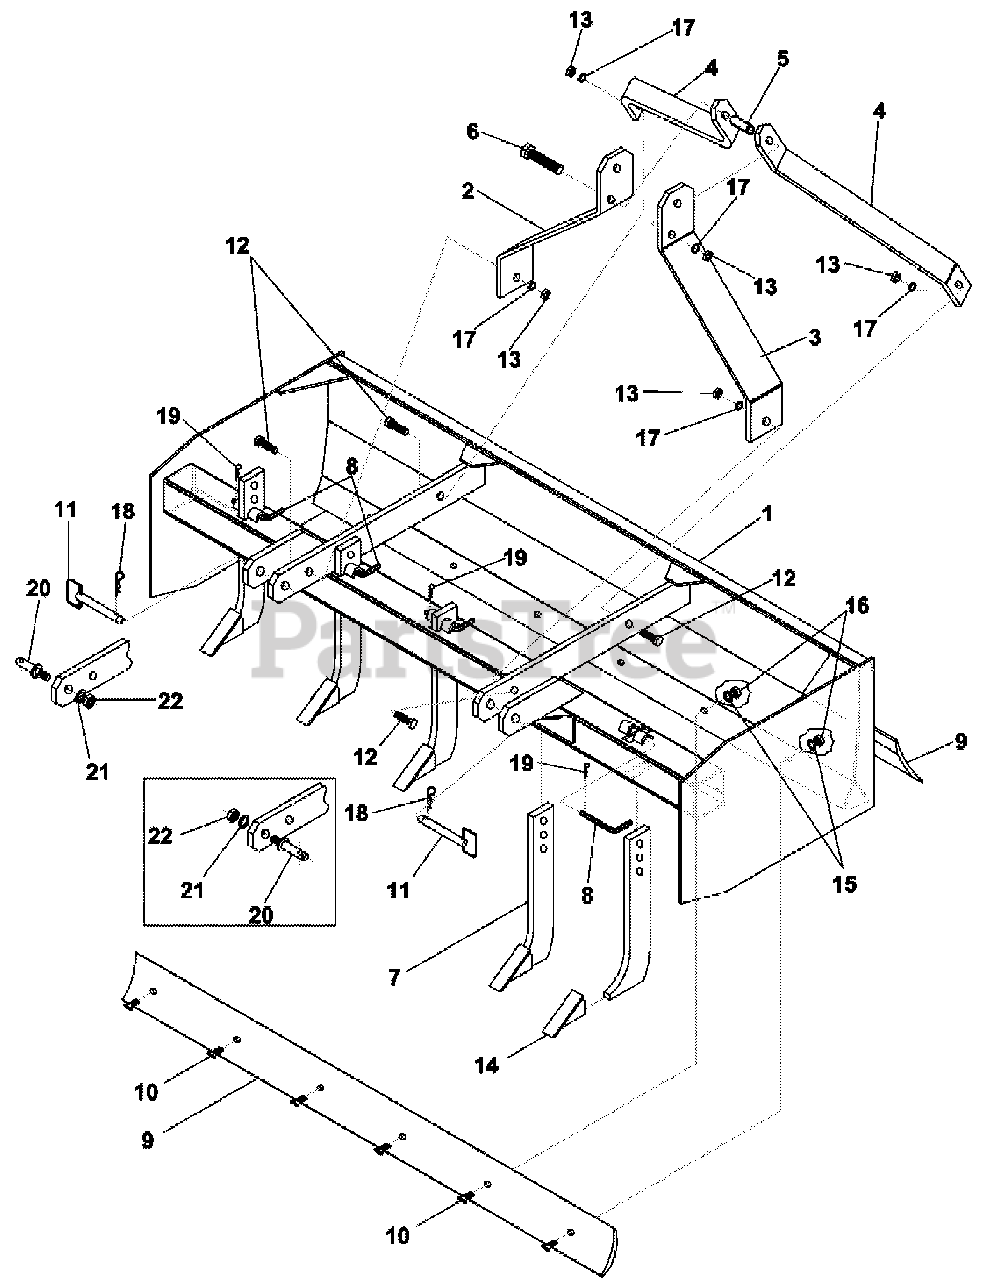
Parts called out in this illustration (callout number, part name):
1	Frame subcompact BS48
2	Vertical support right BS48
2	Vertical support right BS60 & BS72
3	Vertical support left BS48
3	Vertical support left BS60 & BS72
4	Horizontal support BS48
4	Horizontal support BS60 & BS72
5	Inner spacer BS48
5	Inner spacer BS60 & BS72
6	Bolt 3/4"x4.5" BS48
6	Bolt 3/4"x5" BS60 & BS72
7	Scarifier shank
9	Scraper blade BS48
9	Scraper blade BS60
9	Scraper blade BS72
10	Plow bolt 5/8"x1 3/4"
11	Hitch pins BS60 & BS72
12	Bolt 3/4"x1 3/4" BS48
12	Bolt 3/4"x2 1/4" BS60 & BS72
13	Hex nut 3/4"
14	Scarifier tip
15	Lock washer 5/8"
16	Hex Nut 5/8"
17	Lock washer 3/4"
18	R clip Ø4
20	Hitch pins 7/8"x2" BS48 only
21	Lock washer 7/8" BS48 only
22	Hex nut 7/8" BS48 only
